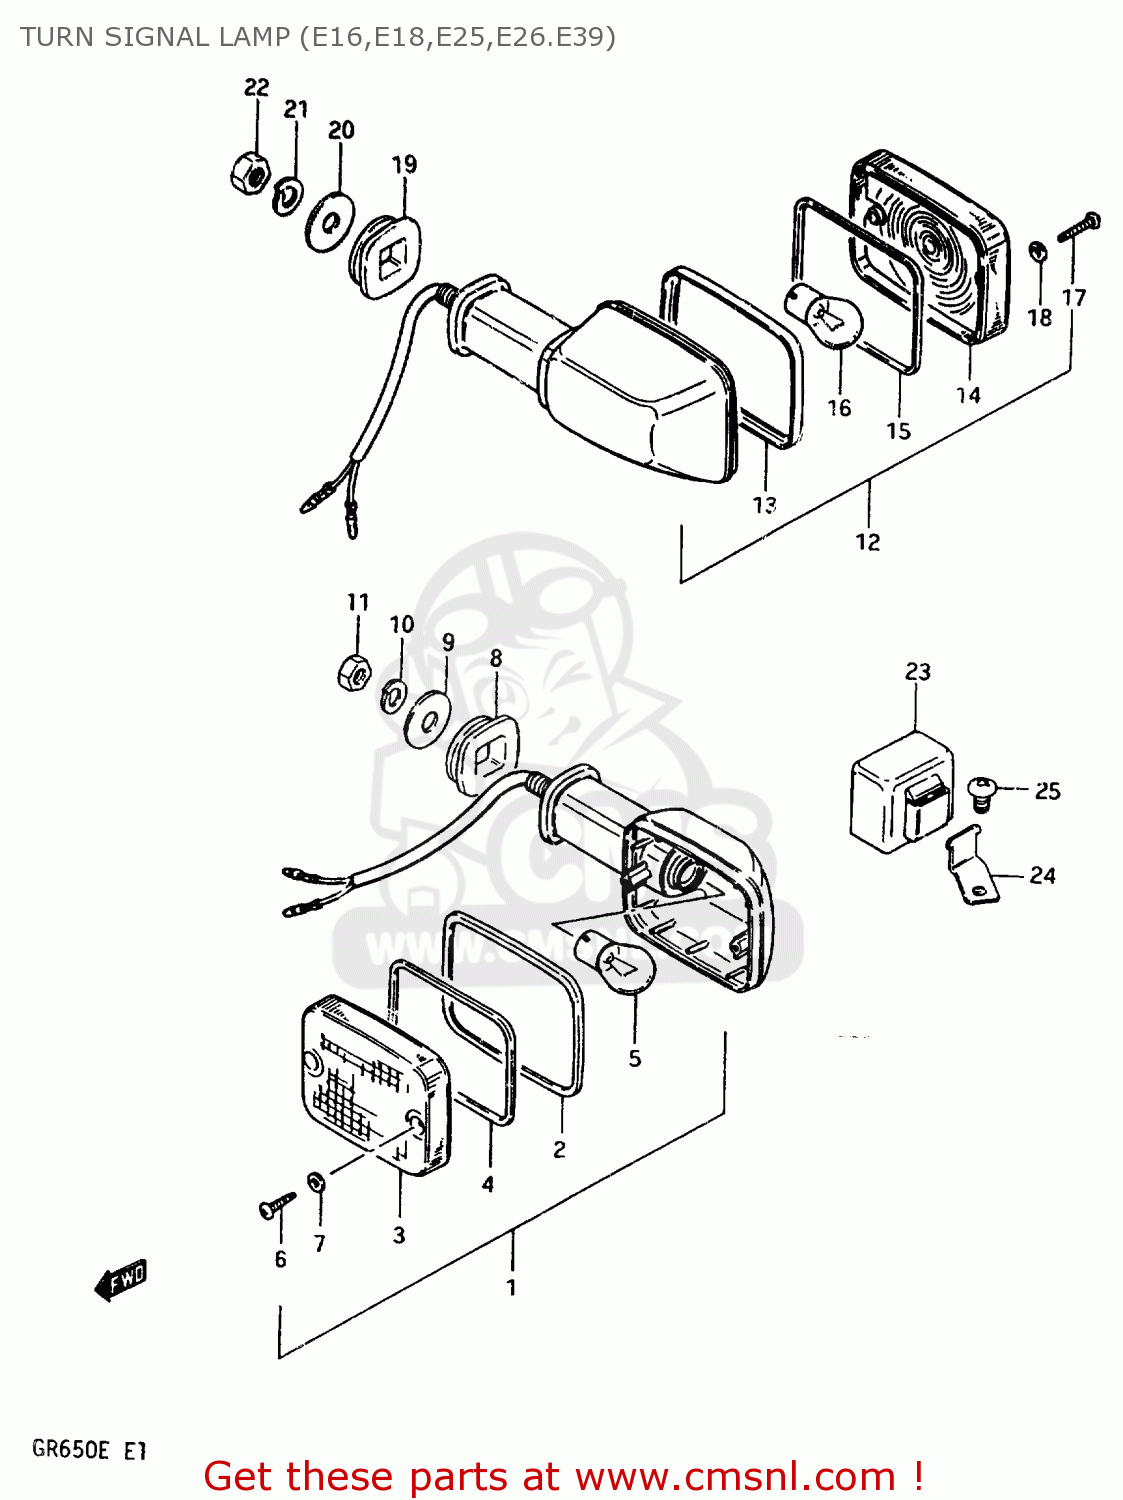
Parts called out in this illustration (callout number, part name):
1	LAMP ASSY, FRONT TURN SIGNAL
2	RIM
3	LENS
4	GASKET (NAS)
5	BULB(12V21W)
6	SCREW
7	GASKET (NAS)
8	CUSHION
9	WASHER (10.5X30X2.3)
10	LOCK WASHER
11	NUT
12	LAMP, REAR TURN SIGNAL
13	RIM
14	LENS
15	GASKET (NAS)
16	BULB(12V21W)
17	SCREW
18	GASKET (NAS)
19	CUSHION
20	WASHER (10.5X30X2.3)
21	LOCK WASHER
22	NUT
23	RELAY,TURN SIGNAL
24	BRACKET,TURN SIGNAL RELAY
25	SCREW
